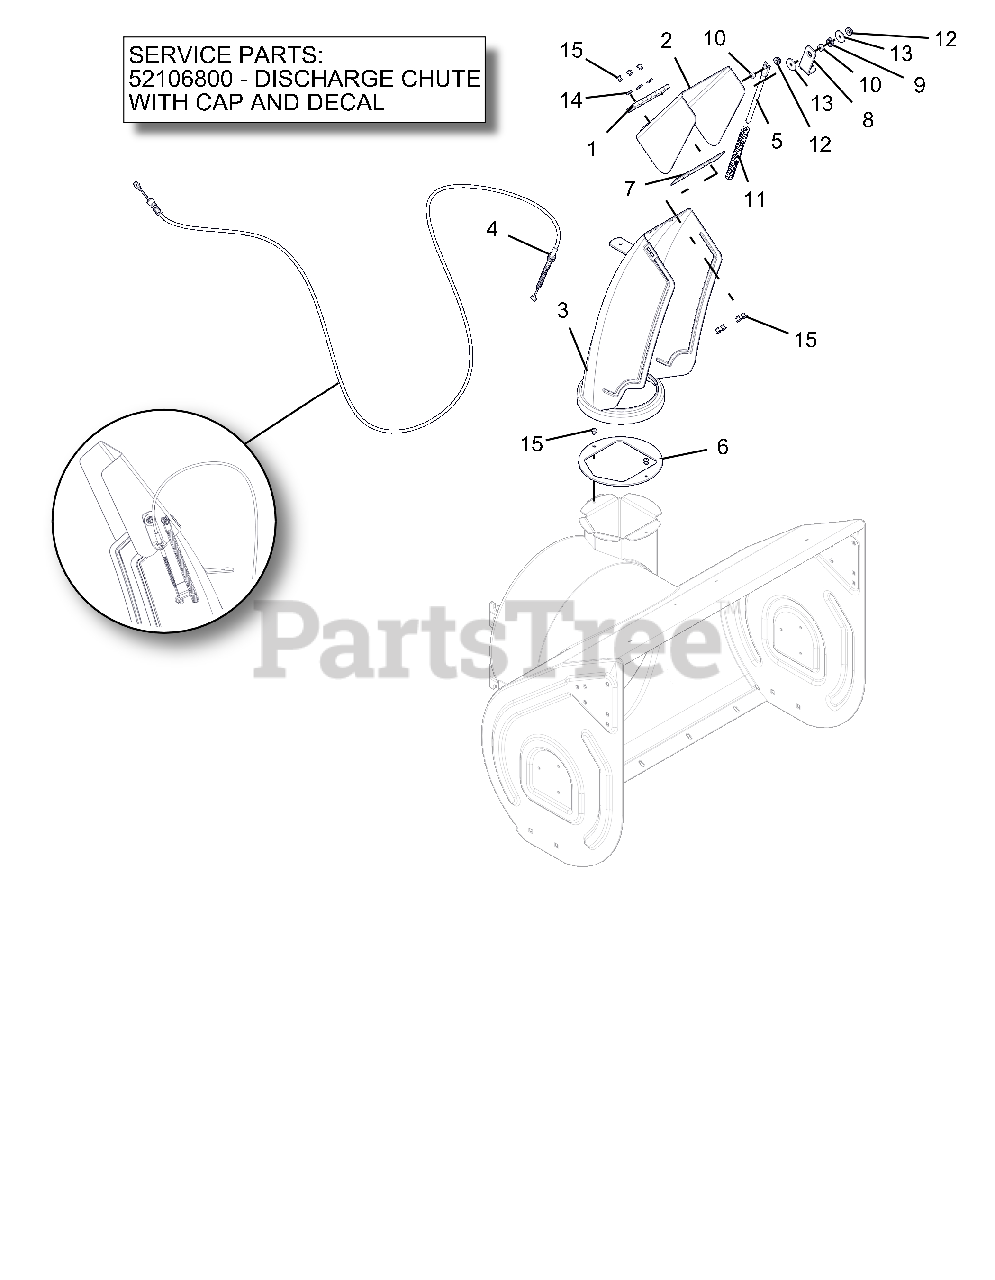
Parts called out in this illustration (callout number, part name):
2	CAP,LARGE,REMOTE
3	CHUTE,DISCHARGE,NOTCHED,QT
4	CABLE, DEFLECTOR - DELUXE
5	ROD, DEFLECTOR CAP
6	BAFFLE, DISCHARGE NECK
7	CAP SEAL 5.50
8	BRACKET, CABLE ANCHOR
9	BUSHING, POLYLINER-.50 SNAPIN
10	BSHG-SLV .265X.500X.219
11	SG-COMP .08X.40X6.50 14#/IN
12	@NUT-LK-CTR-FLG .25-20 YWZC
13	WSHR-FL-STL .281X1.000X.063
14	WSHR-FL-STL .196X.500X.06 YZ
15	RVT-POP .187 YZ
16	KIT, DISCHARGE CHUTE W/DEF QT2
